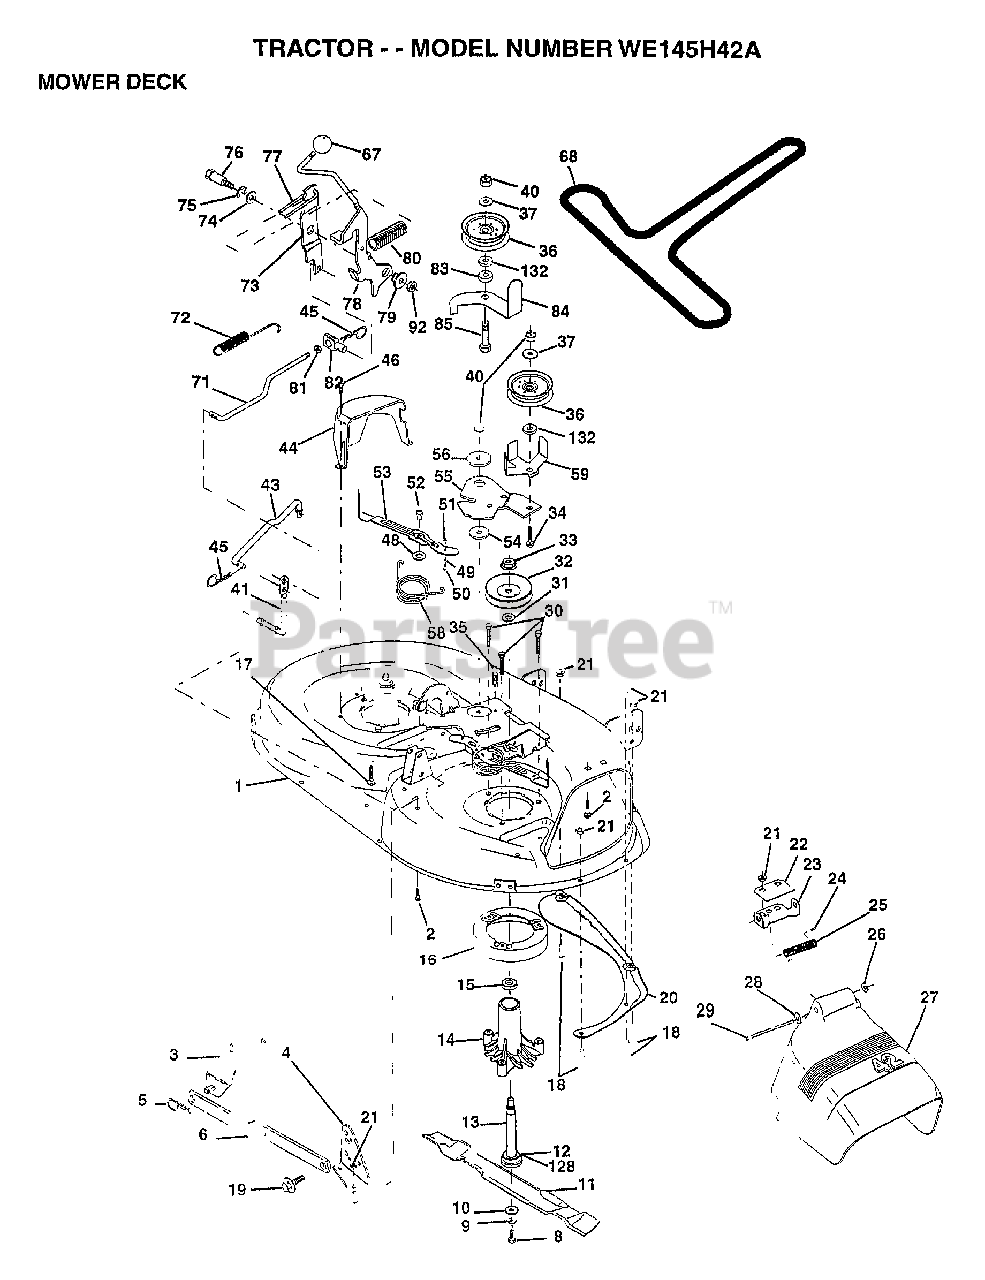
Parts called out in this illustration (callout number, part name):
1	DECK.WELD.42.
2	BOLT
3	BRKT ASM SWAY BAR
4	BRKT DECK SW BAR
8	BLADE BOLT
10	WASHER.HARD.BLADE
11	"BLADE.42"" HIPERF"
12	BEARING.BALL
14	HSG ASM MANDREL
15	BEARING
16	STRIPPER RND MWR
17	BOLT RDHD 3/8-16
18	BOLT
19	BOLT SHD 5/16-18
22	STIFFENER BRKT
23	DEFLECTOR BRKT
24	CAP-SLEEVE LT
25	SPRING TORSION
26	NUT PUSH M
27	DEFLECTOR.SHIELD
28	WASHER
29	HINGE ROD
31	WASHER
32	PULLEY.MANDREL.42
34	BOLT
35	XMAS TREE FASTNER
36	FLAT IDLER PULLEY
37	WASHER
41	PIVOT ROD
43	ROD CLUTCH W/NIBS
44	GUARD MAND LH BLK
45	RETAINER M
46	SCREW.1/4-20X5/8
48	HARD SMALL WASHER
49	ROLLER ASM-CAM
50	SHOULDER BOLT
51	LOCKNUT
52	BOLT.SHLD.5/16-18
54	HARDENED WASHER
55	ARM-IDLER
56	SPACER RETAINER
58	SPRING TORSN BRAK
59	GUARD IDLER TUV
67	KNOB T(3/8 HOLE)
68	BELT.V.T-PATH
71	ROD CLUTCH 38/42
72	RETURN SPRING
73	CLUTCH ARM SECOND
74	WASHER
75	RING
76	SHOULDER BOLT
77	SPRING KEEPER
78	LEVER ASM-CLUTCH
79	BUSHING
80	SPRING.CLUTCH.MWR
81	NUT
82	TRUNION ADJ
83	WASHER
84	"KEEPER-BELT,FIXED"
85	BOLT RDHD 3/8-16
92	NUT
128	WASHER.FELT.
132	WASHER GT
